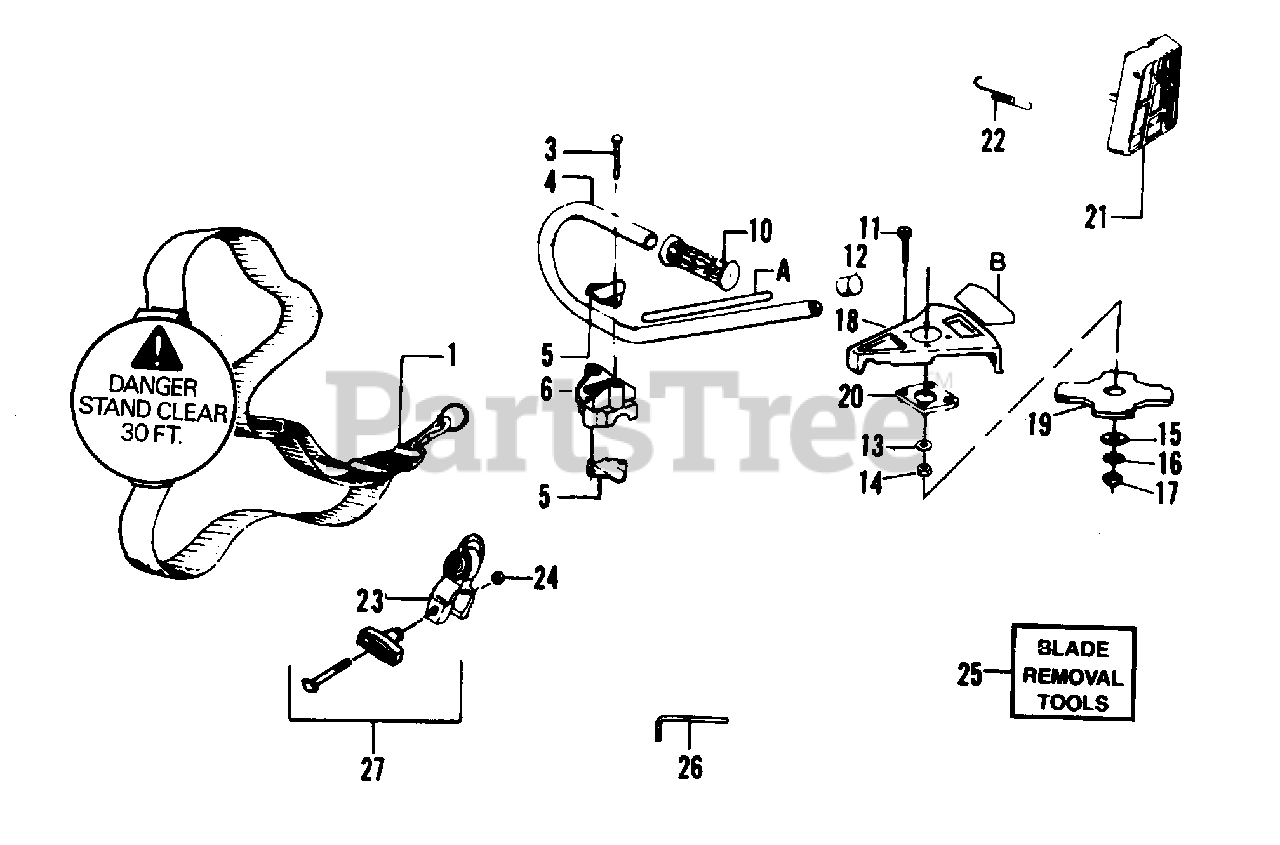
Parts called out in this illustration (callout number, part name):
1	Shoulder Strap (inc. Key Ring)
3	Bolt-1/4-20x2" Hex
4	Barrier Handlebar
5	Handlebar Bracket
6	Handlebar Clamp
10	Grip-Handlebar
11	Screw-#1/4"-20x1" Hex
12	End Cap Handlebar
13	Washer-1/4" Flat
14	Nut-Deflector to Brg. Hsh. (#1/4-20)
15	Washer-Flat
16	Washer-Bevel
17	Flange Nut
18	Shield-Aluminum
19	Blade-4 Tooth Weed
20	Shield Retention Plate
21	Muffler Guard
22	Muffler Guard Spring
23	Clamp Harness Ass'y
25	Blade Removal Tools
26	Hex Wrench
27	"T" Handle Kit
A	Decal-Handlebar Warning
B	Decal-Blade Rotation Warning
